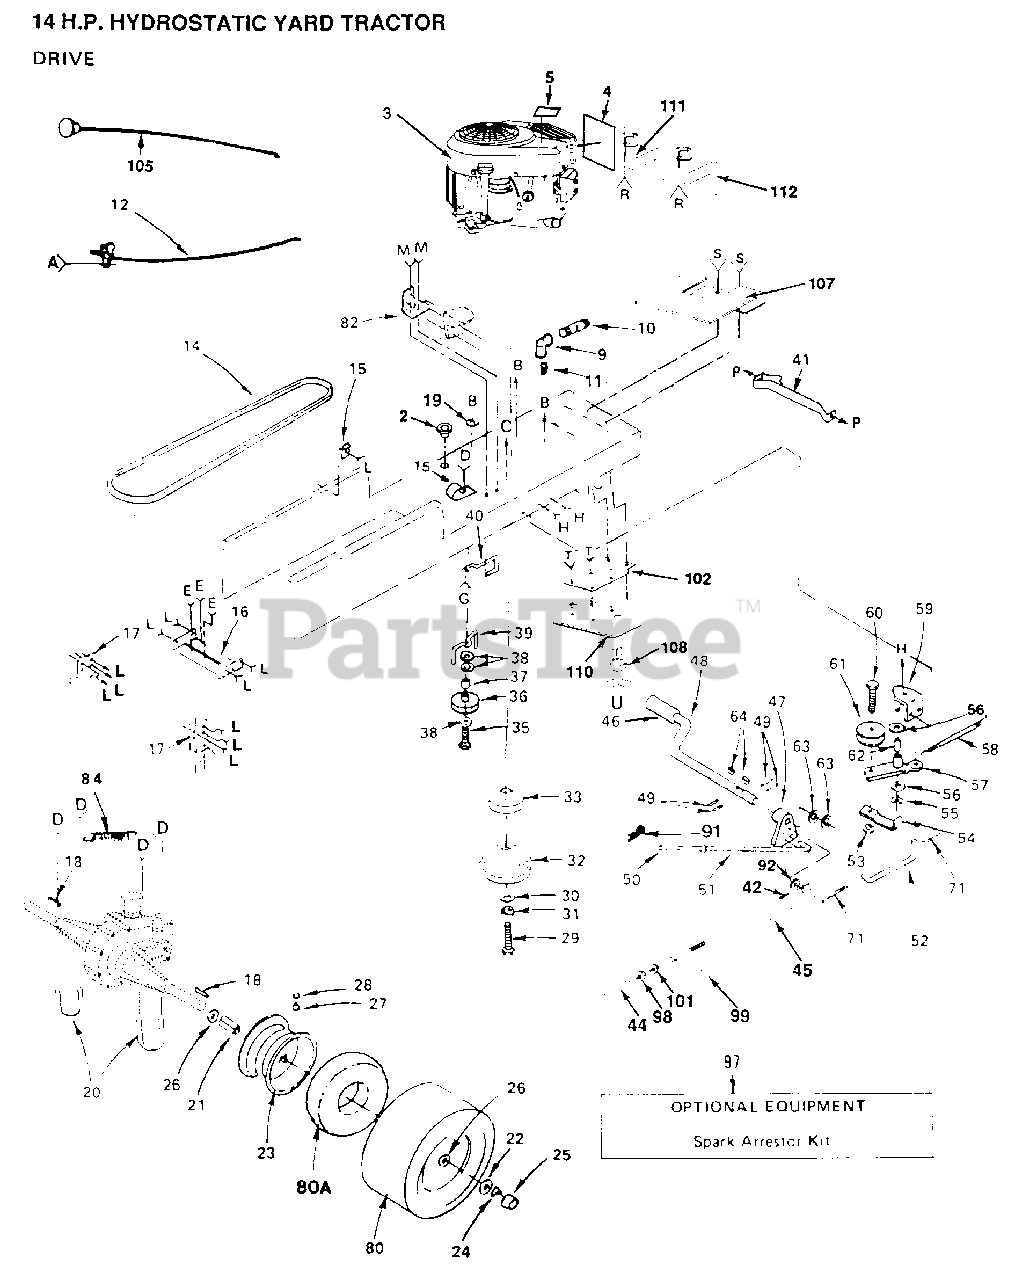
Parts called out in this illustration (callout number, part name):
3	PIPE, EXHAUST
4	DECAL, ENGINE INSTRUCTION
5	DECAL, MAINTENANCE
9	ELBOW
10	PIPE NIPPLE LT
11	PLUG OIL DRAIN
15	CLIP T
16	PLATE TRANS SUPT
18	SQUARE KEY
19	NUT
20	U BOLT
21	SPACER SPLIT
22	WASHER
24	E-RING LT
25	HUB CAP
26	BOLT, METRIC
27	VALVE STEM LT
28	VALVE CAP
30	WASHER LT
31	LOCKWASHER
35	BOLT
36	PULLEY.IDLER.FLAT
37	SPACER T
38	WASHER
39	"KEEPER,BLT ENG LT"
40	KEEPER BELT ENGLH
42	COTTER PIN
44	SPRING ROD LT
45	ROD BRAKE
46	PEDAL COVER T
50	PLUNGER CAP T
52	"LINK, CLUTCH T"
54	BELT KEEPER LT
55	KLIP RING
56	WASHER LT
57	"ASS T, BELLCRAN"
58	"SPRING, RETURN LT"
62	"LY, BEARING"
63	WASHER LT
71	COTTER PIN
80A	TUBE.18X9.5-8
82	No Desciption for Part
91	SPRING.RETAINER
92	WASHER
98	NUT
99	RETAINER M
101	NUT
102	BRACKET MUFFLER
108	DEFLECTOR.222573
111	TUBE ASSY EXH RH
112	TUBE ASSY EXH LH
